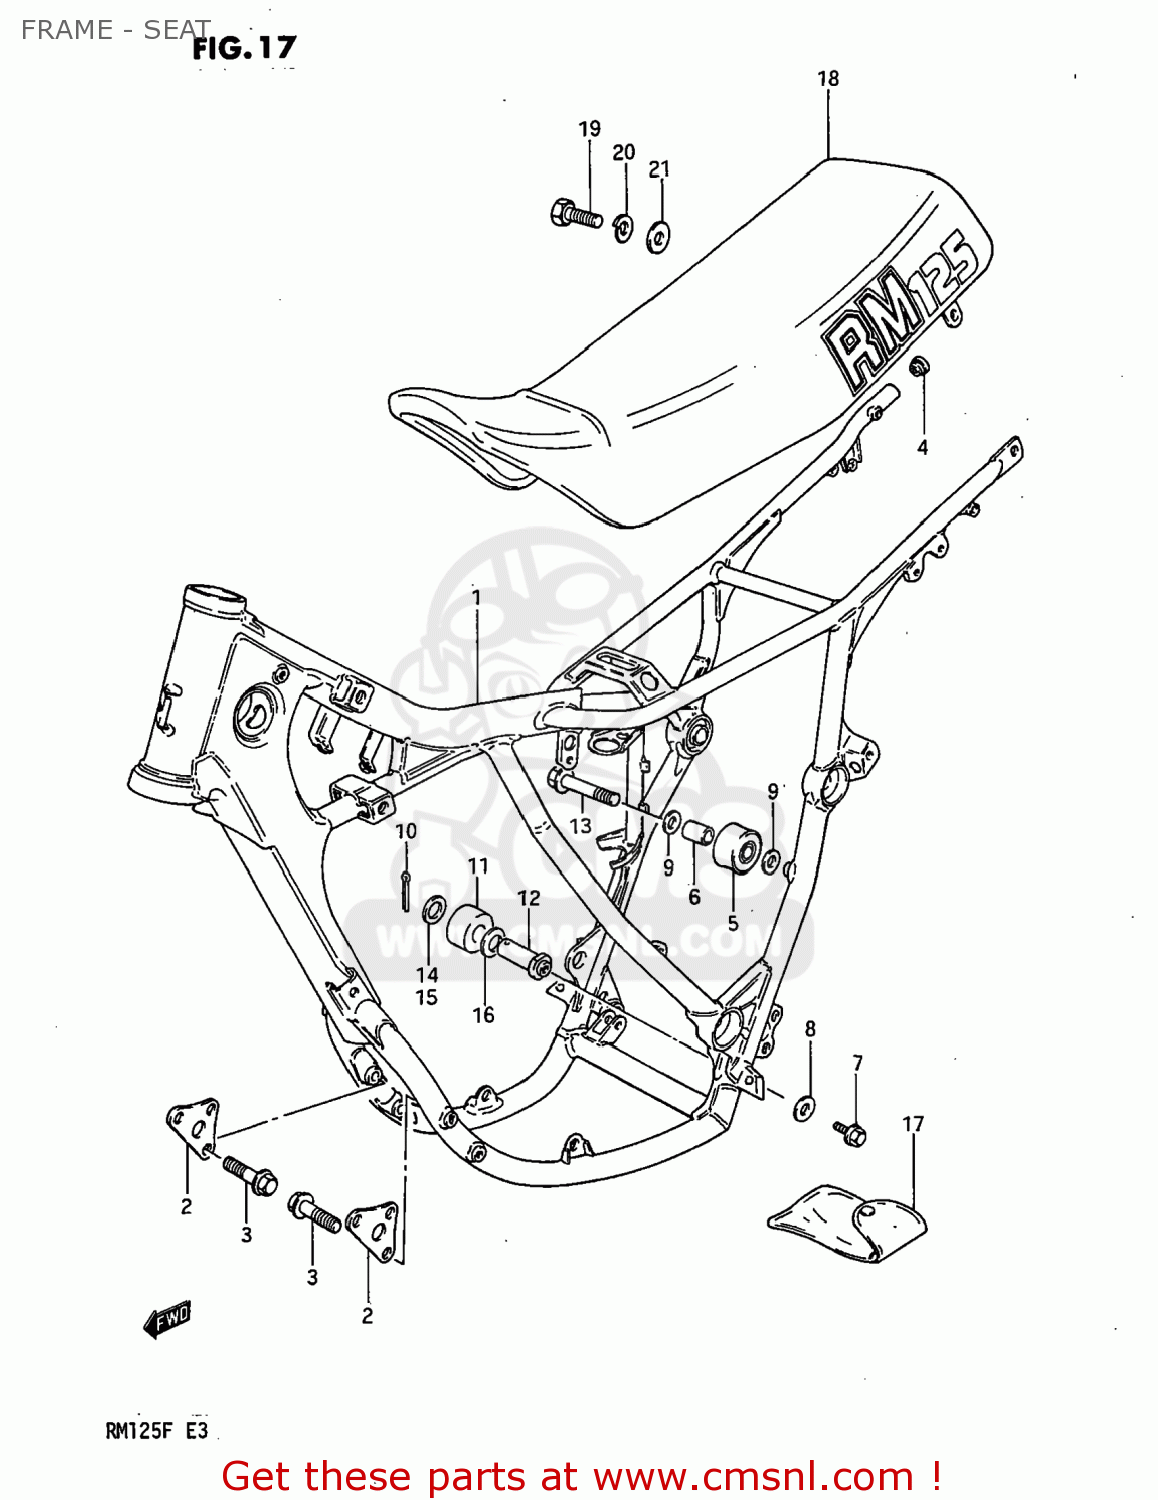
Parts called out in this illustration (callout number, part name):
1	FRAME
2	PLATE,ENGINE MOUNTING
3	BOLT(8X36)
4	CAP(OD:19)
5	ROLLER,CHAIN
6	SPACER(8.6X12X25.5)
7	BOLT
8	WASHER
9	WASHER
10	PIN 25X20
11	ROLLER,CHAIN LENGTH CONTROL
12	BOSS,CHAIN LENGTH ROLL
13	BOLT(8X45)
14	WASHER
15	WASHER
16	WASHER
17	TOOL SET
18	SEAT ASSEMBLY
19	BOLT
20	LOCK WASHER
21	WASHER
